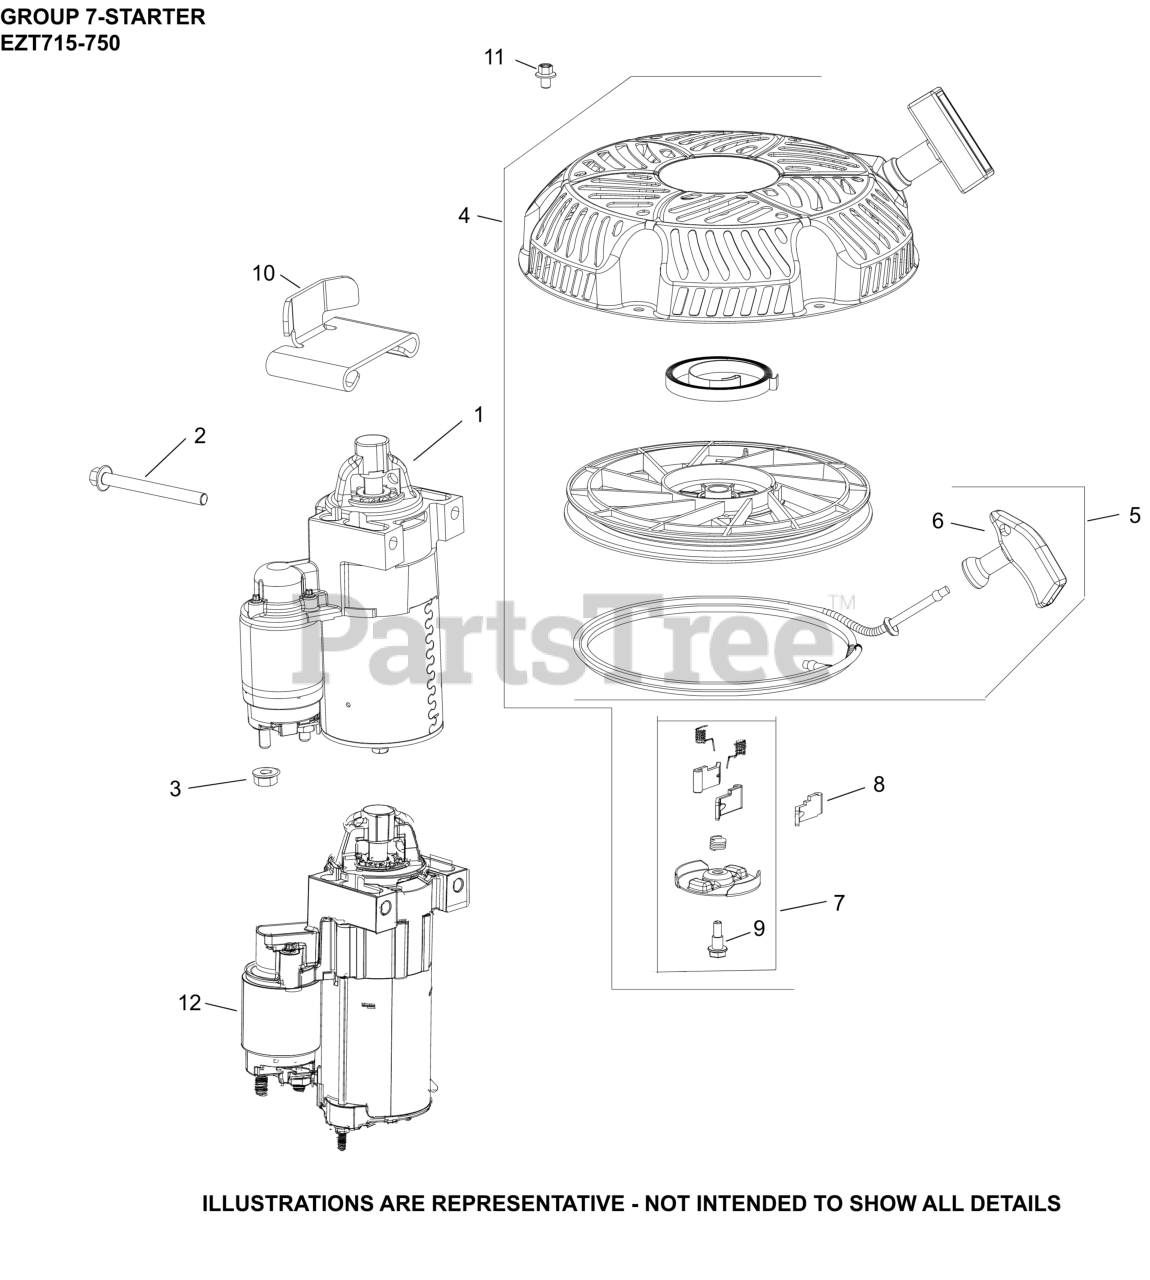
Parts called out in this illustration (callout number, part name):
1	STARTER, SOLENOID SHIFT
2	SCREW, FLG M8X1.25X80
3	NUT, FLG M8X1.25
